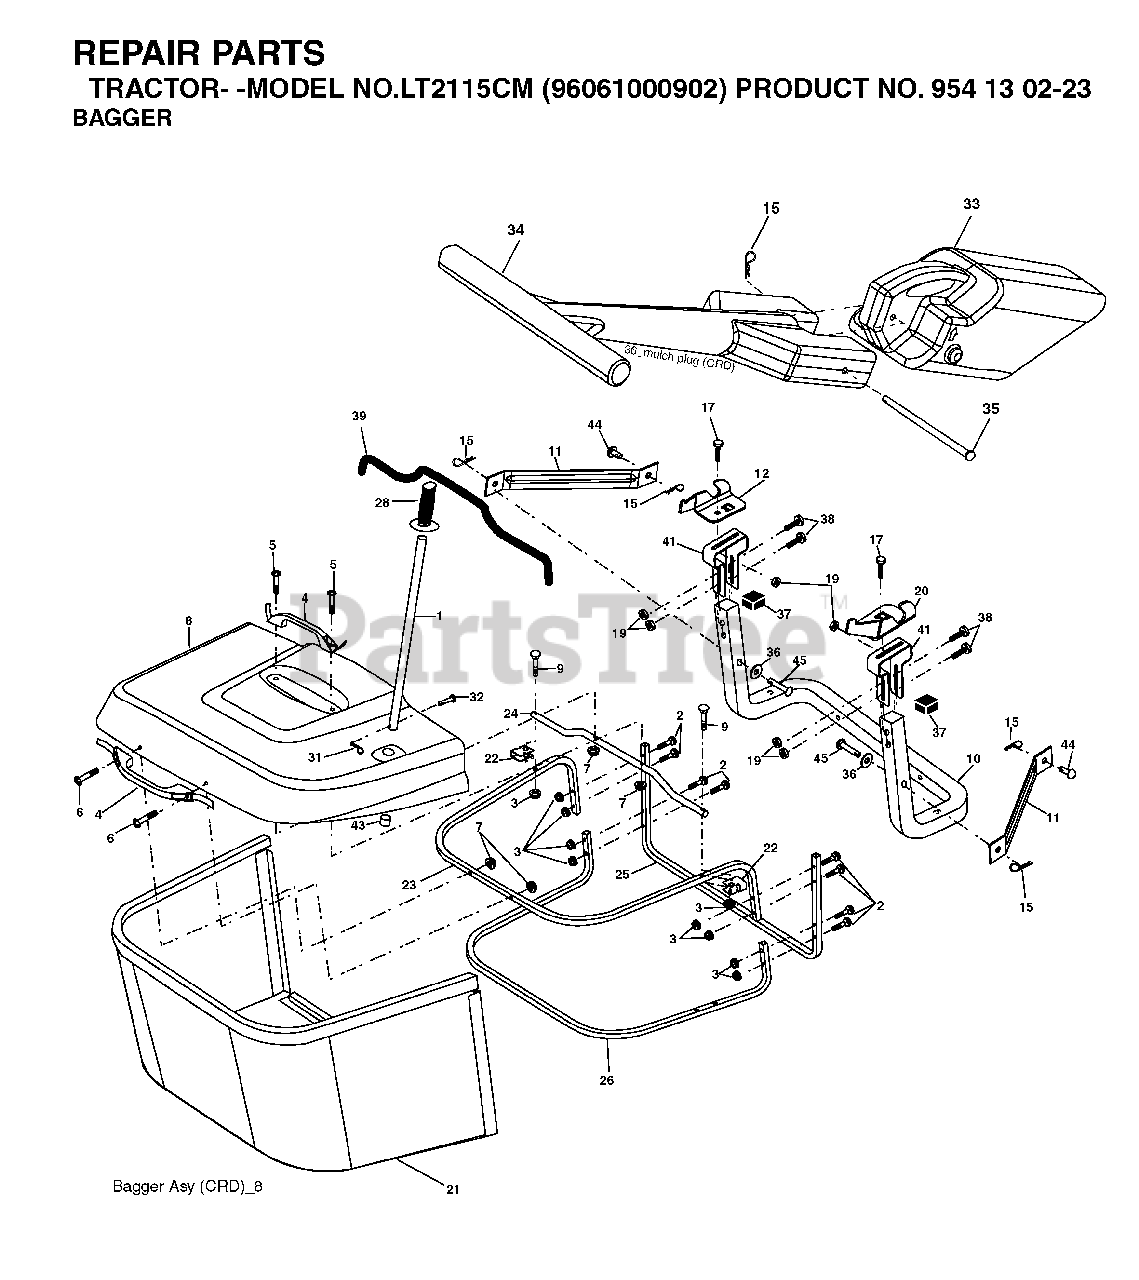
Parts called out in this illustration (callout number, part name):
1	TUBE HANDLE
3	NUT T
5	SCREW.PAN.HEAD
11	BRACKET
15	RETAINER-SPRNG RB
17	BOLT
19	NUT LOCK HEX FLANGE 5/16-18
20	BRKT.PIVOT.RH.CRD
21	GRASS BAG
22	BRACKET
23	TUBE
24	TUBE
26	TUBE
28	GRIP.HANDLE.BLACK
31	RETAINER CLIP
32	RIVET,DRILLED
33	PLUG
35	PIN
38	BOLT.5/16-18X2.5
41	BRKT, BAGGER
43	PLUG, TUBING END
